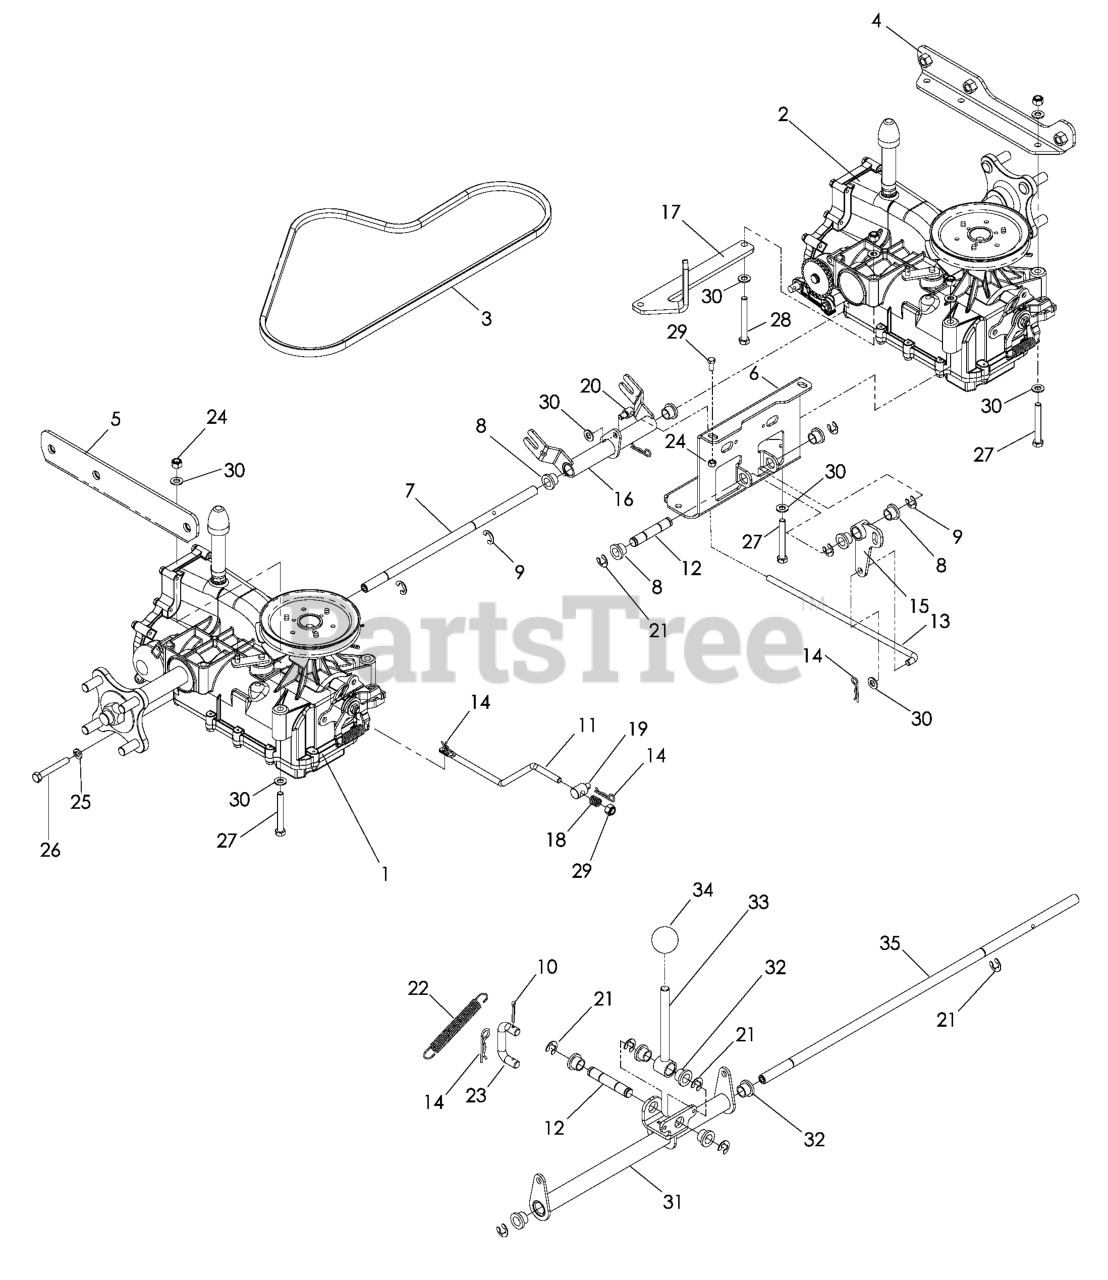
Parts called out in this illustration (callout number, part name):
1	HG_IZT LEFT (354-2400R)
2	HG_IZT RIGHT (354-2400L)
4	IZT SUPPORT RIGHT
5	IZT SUPPORT, LT
6	IZT SUPPORT, REAR
7	IZT CONNECTOR
8	BUSHING, FLANGED NYLON
9	E-RING 1/2 (2 2)
10	COTTER PIN 3/32 X 3/4
11	IZT BYPASS LINKAGE
13	BRAKE LINKAGE
14	HAIRPIN #2
15	BRAKE BELLCRANK, REAR
16	BRAKE BELLCRANK, FRONT
17	CLUTCH TIE DOWN
20	SWIVEL (SHORT)
21	E-RING 1/2 (2 2)
23	BRAKE ENGAGE LINKAGE
24	NUT 5/16 NYLOC
25	WASHER.LOCK.HVY.HLCL.SPR.5/16
26	HEX SCREW-.313C X 2.25 GR8
27	BOLT 5/16C X 2 1/2
28	HCS 5/16C X 2-3/4
29	HCS 5/16C X 3/4
30	FLAT WASHER 5/16 SAE
31	ACTUATOR ARM
32	BUSHING, FLANGED NYLON
